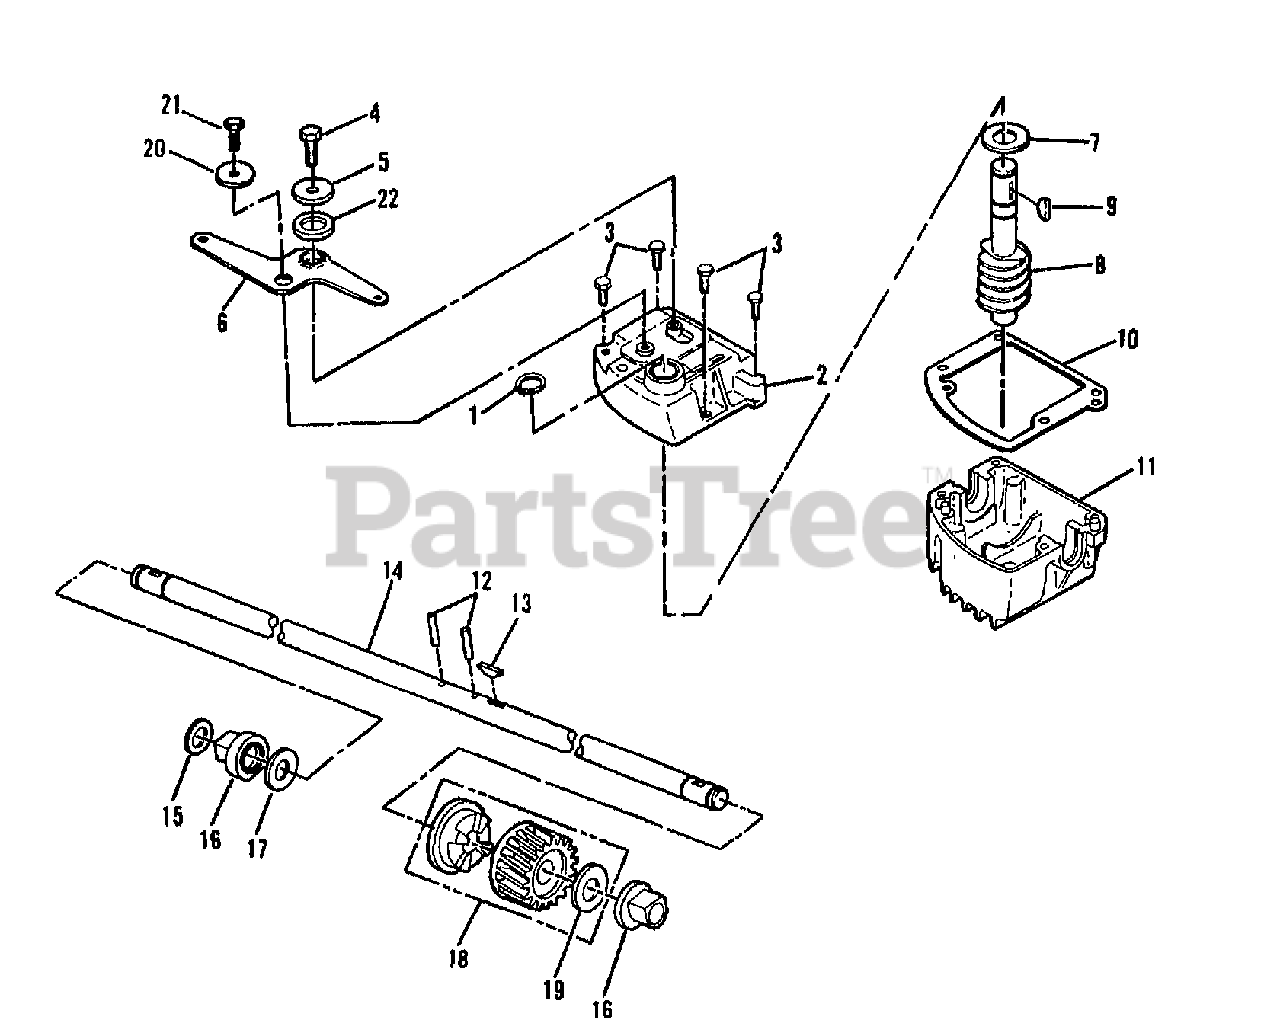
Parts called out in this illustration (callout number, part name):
1	RING-RETAINING
2	ASSM-HOUSING
3	HEX S.T. NO. 8-32 x 1/2" BOLT
4	SCR-TRUSS #10-24 X 5/8
6	LEVER-CLUTCH
8	SHAFT-INPUT
9	KEY-WDRF
11	ASSM-HOUSING
13	KEY-HI PRO
14	SHAFT-OUTPUT
16	ASSM-BRG & SEAL
18	HELICAL GEAR & CLUTCH DOG ASSEMBLY, KIT
20	WASHER-.505X.22X.05 (TRANSMISSION 1747891)
21	SCREW, TAPPING 10-24 x 1/2 (TRANSMISSION 1747891)
22	FOAM SEAL
